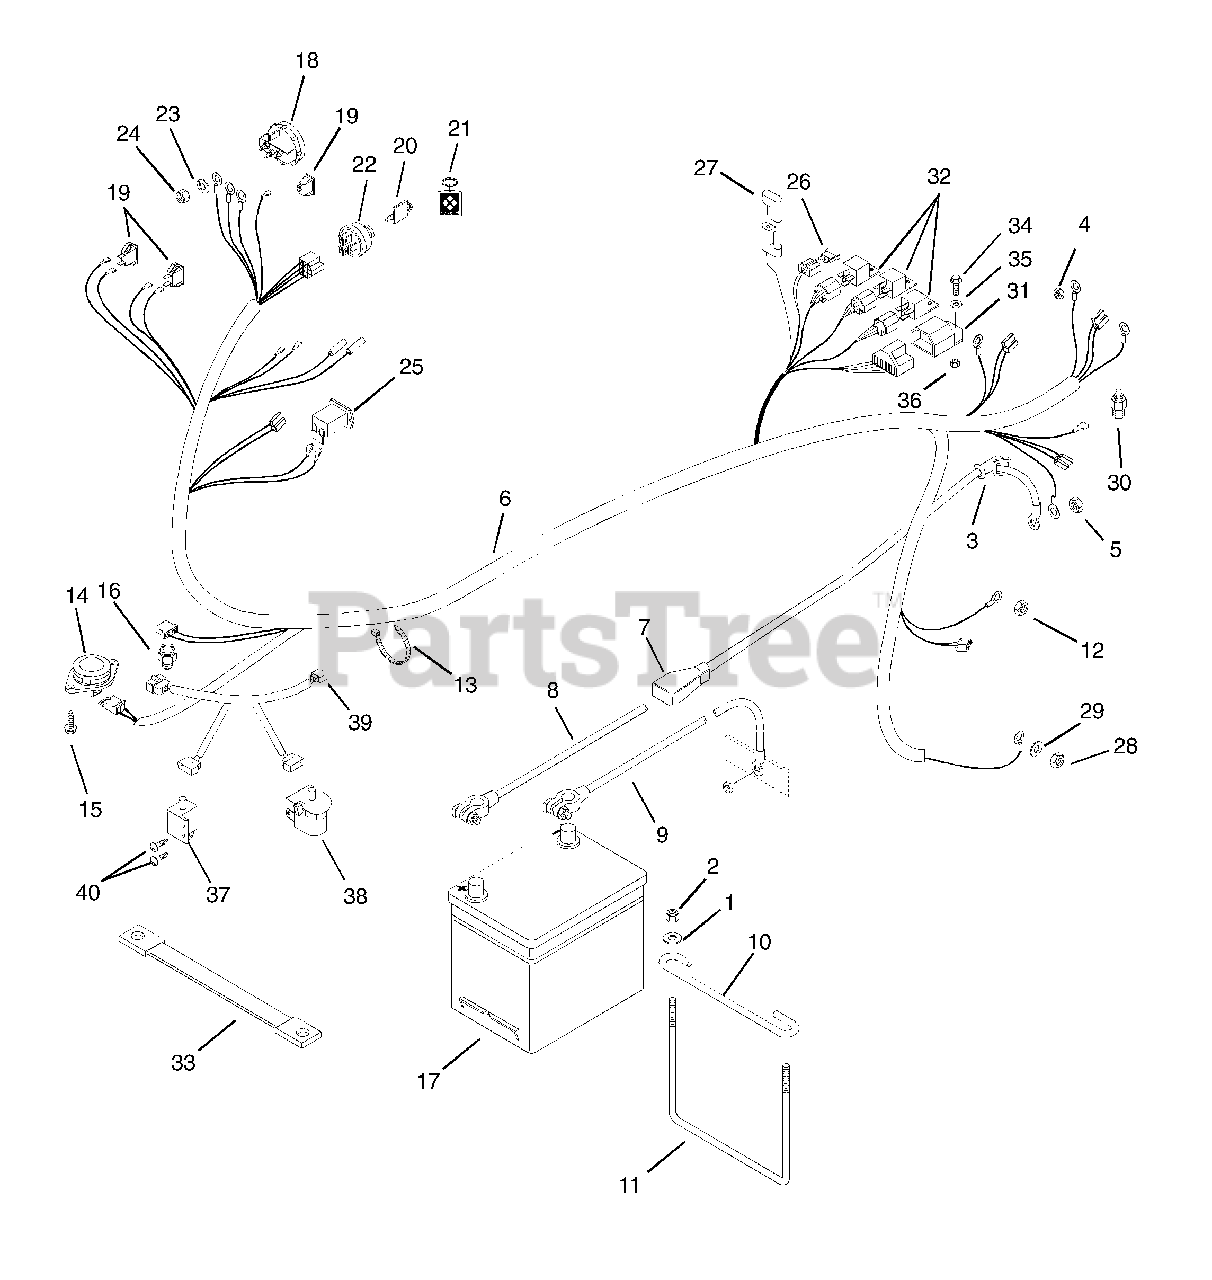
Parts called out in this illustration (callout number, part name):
1	Washer-Flat Steel .281 x .625 x .065
2	Nut-Locking-Nylon .25-20
3	Boot, Insulator
4	Nut-Hex M5 x .8
5	Nut-Hex M8 x 1.25
6	Wire Harness, Kubota
7	Cover, Battery Terminal
8	Cable, Positive Battery
9	Cable, Negative Battery
10	Rod, Hold Down
11	Rod, Battery
12	Nut-Hex .31-18
13	Tie Wrap, Black
14	Seat Switch
15	Screw-Tapping 12-24 x .50 Hex Washer Head
16	Switch-Neutral Start
17	Battery, 24V
18	Gauge, Temperature
19	Light, Indicator
20	Ignition Switch Key
21	Key Chain
22	Switch, Ignition (Diesel)
23	Washer-Lock #10 x .047 Regular
24	Nut-Hex 10-32
25	Hour Meter
27	Molded Diode Plug, 1 AMP
28	Nut-Hex M6 x 1.00
29	Washer-Flat-Steel .281 x .620 x .065
30	Temperature Sender
31	Module, Time Delay
32	Relay
33	Ground Strap (Engine to Frame)
34	Screw-Machine 10-24 x .75 Hex Washer Head
35	Washer-Flat-Steel .219 x .50 x .049
36	Nut-Locking-Nylon 10-24 w/Insert
37	Switch-Single N.O.
38	Switch-Snap Mounting N.O.
39	Insert-PM-400 Kubota CE Certificate
40	Screw-Tapping 12-24 x .50 Hex Washer Head Thread Rolling
